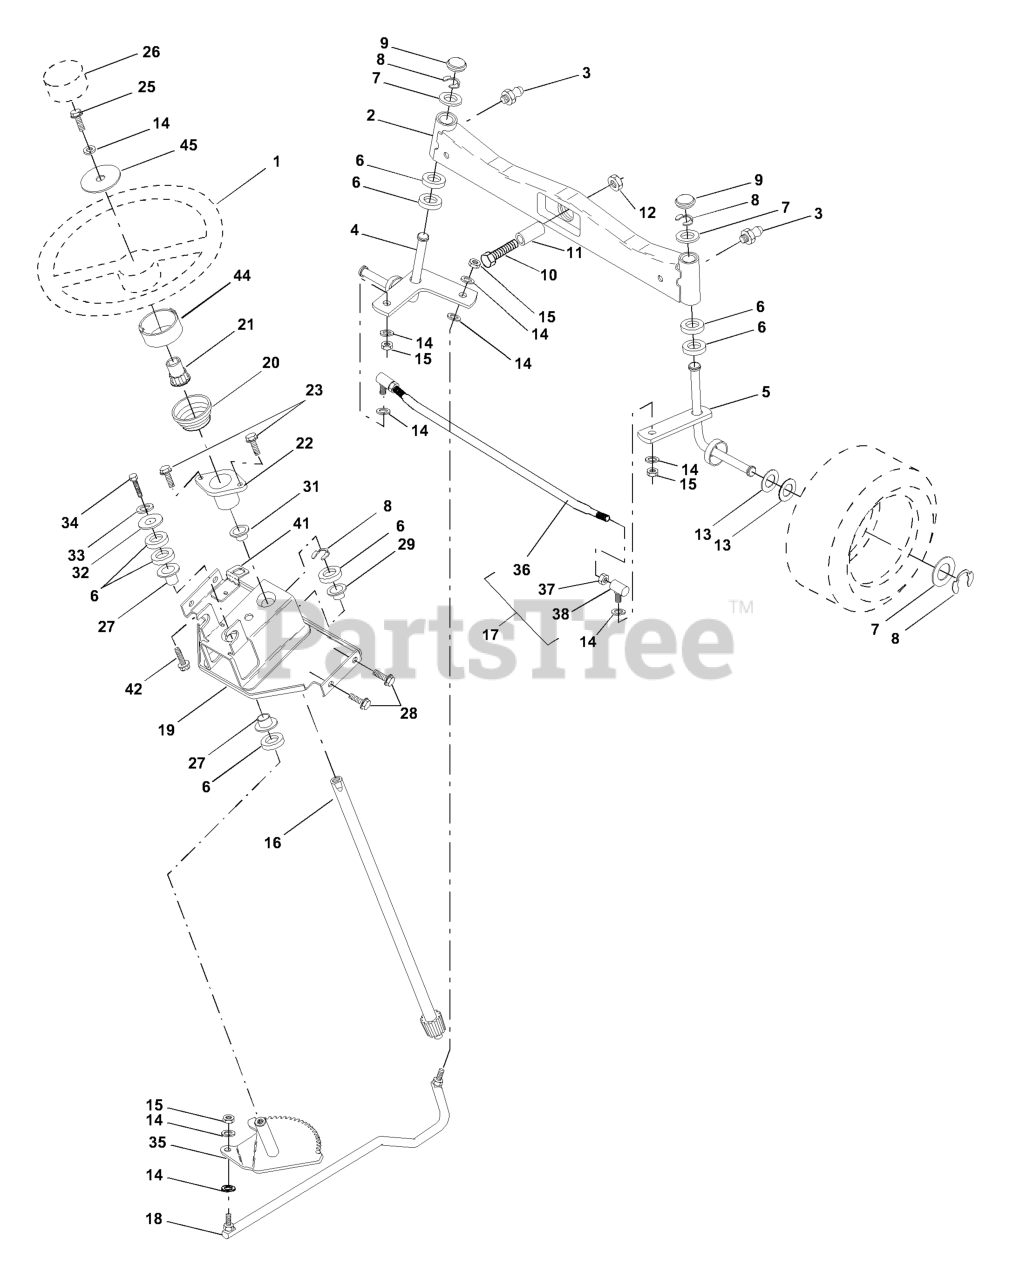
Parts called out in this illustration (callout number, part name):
1	STEERING WHEEL
2	FRONT AXLE ASSY
3	ZERK M
4	SPINDLE ASSY LH
5	SPINDLE ASM RH
6	THRUST WASHER
9	CAP.SPINDLE.BLACK
10	Bolt, Fin Hex 5/8-11 x 2-3/4
11	TUBE, PIVOT AXLE
12	NUT-LOC,FLANGE LT
14	WASHER, LOCK 3/8
15	GRIPCO NUT
16	SHAFT ASM, STEERING
17	ROD ASM TIE BALL
18	DRAGLINK-BALL JOINT SOLID
19	SUPPORT ASM., STEERING VGT
20	BOOT, STEERING
21	STEERING WHEEL ADAPTOR
22	BUSHING, STRG. BLK
23	SCREW.TT.#10-32X.5.3/8.FLANGE
25	BOLT
26	STEERING WHEEL
27	BRNG T
28	SCREW, 3/8-16X3/4
29	BEARING-FLANGE GT
31	BUSHING.NYLINER.
33	WASHER.LOCK.HVY.HLCL.SPR.5/16
34	BOLT.FIN.HEX.5/16-18X3/4
35	GEAR.ASM.SECTOR.
36	TIE ROD
38	JOINT
41	BRACKET INTERLOCK
42	Screw 5/16-18 x 1/2
44	EXTENSION STEERING PREMIUM
45	Washer 13/32 x 1-1/20 x 11 Ga.
